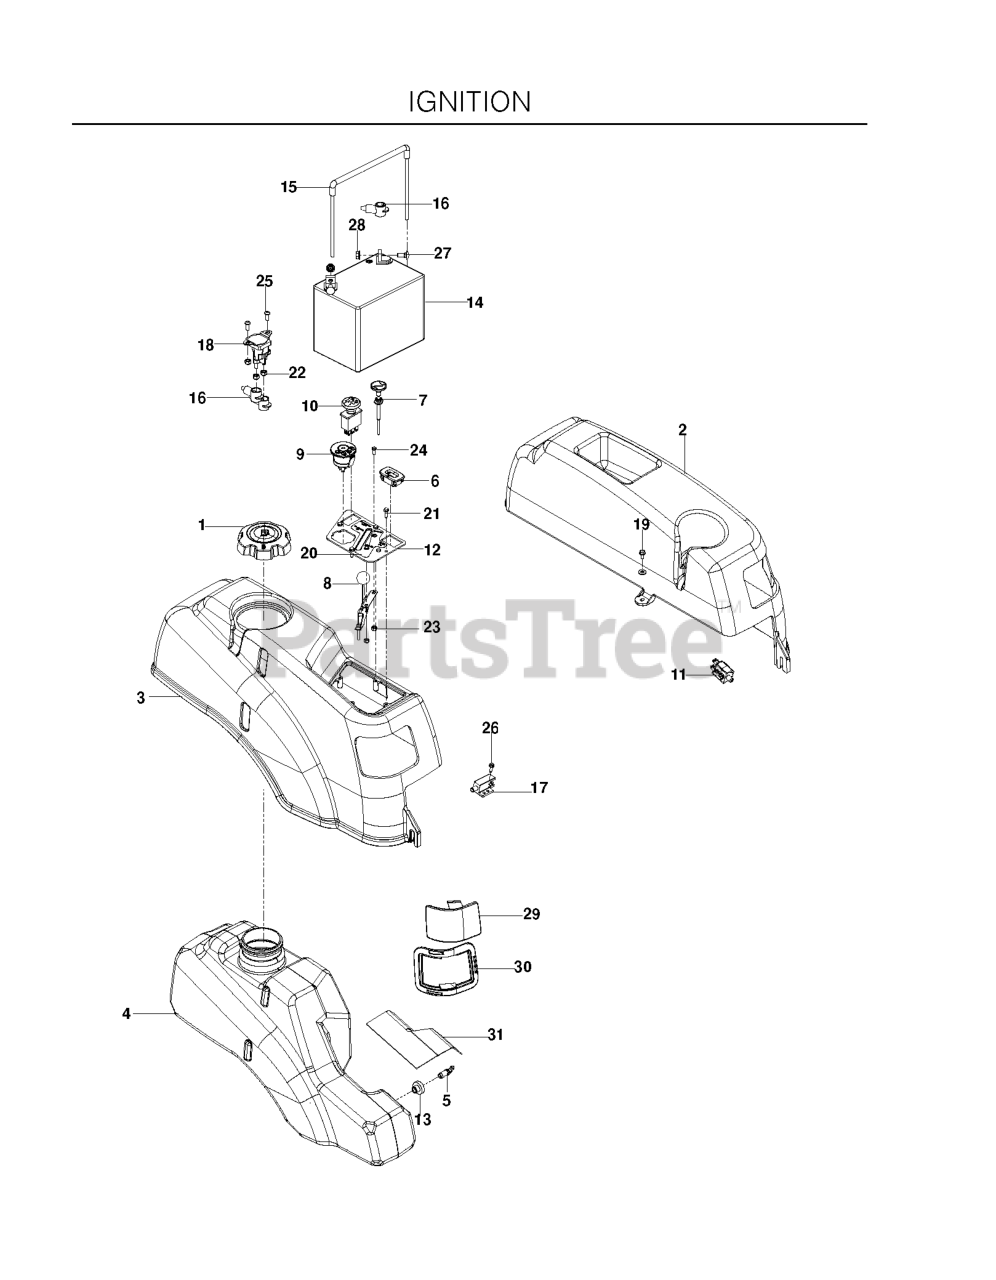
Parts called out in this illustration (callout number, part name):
1	FUEL CAP, HTC
2	FENDER, LT
3	RP.FENDER, RT
4	TANK, FUEL
5	STEM, FUEL TANK
6	HOUR METER
7	CHOKE CONTROL, COMPLETE
8	THROTTLE CONTROL W/BALL KNOB
9	RP IGNITION SWITCH
10	RP.SWITCH, BLADE
11	SWITCH, BRAKE 3P
12	CONSOLE.PLATE.BLACK
13	RUBBER GROMMET
14	BATTERY, 12 V 330 AMP
15	BATTERY TIE DOWN ASSEMBLY
16	TERMINAL COVER-SM
17	SWITCH, INTERLOCK
19	BOLT 1/4-20 X 1/2 HWST
20	DECAL, IGNITION CONSOLE
21	HCS #10-24 X 1/2
22	NUT.1/4-20.HEX.NYLOC.ZD
23	NUT 10-24 NYLOC
24	SCR #10-12X3/4 HEX WAS HD ZD
25	SCR 1/4-20 X 5/8 BTN SKT HD ZD
26	SCREW #10 X 1/2 SELF TAPPING
27	BOLT 5/16C X 3/4" CARRIAGE
28	NUT 5/16C WHIZ
29	LENS, COLORED LEFT
29	LENS, COLORED RIGHT
30	LEFT HEADLIGHT RIM GREY
30	RT HEADLIGHT RIM GREY
31	SHIELD, HEAT
